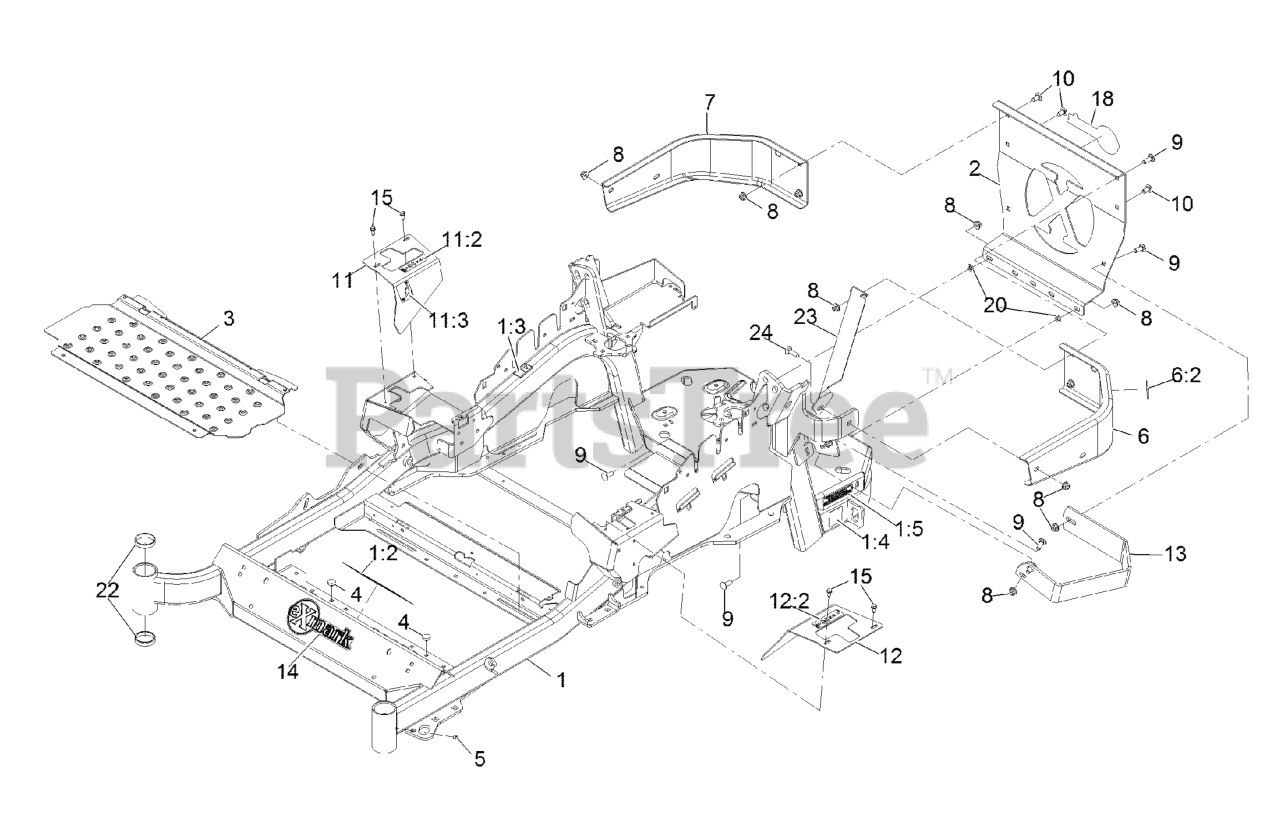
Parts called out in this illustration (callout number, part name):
1	MAINFRAME ASM
1:2	DECAL-DANGER
1:3	DECAL-WARNING
1:4	DECAL-HAZARD, PINCHED FINGER
1:5	DECAL-ARRESTOR, SPARK
2	PLATE,REAR GUARD
6	LH BUMPER ASM
6:2	DECAL-WARNING
7	BUMPER-RH
8	NUT-HF, NI
9	SCREW-CARR
10	SCREW-CARR
11	RH MOTION CONTROL COVER ASM
11:2	DECAL-CONTROL, MOTION
11:3	DECAL-PARK BRAKE, CE
12	LH MOTION CONTROL COVER ASM
12:2	DECAL-CONTROL, MOTION
13	GUARD-MUFFLER
14	DECAL-EXMARK
15	SCREW-HWH
20	NUT-PUSH
22	CUP-BEARING
24	BOLT-CARR
